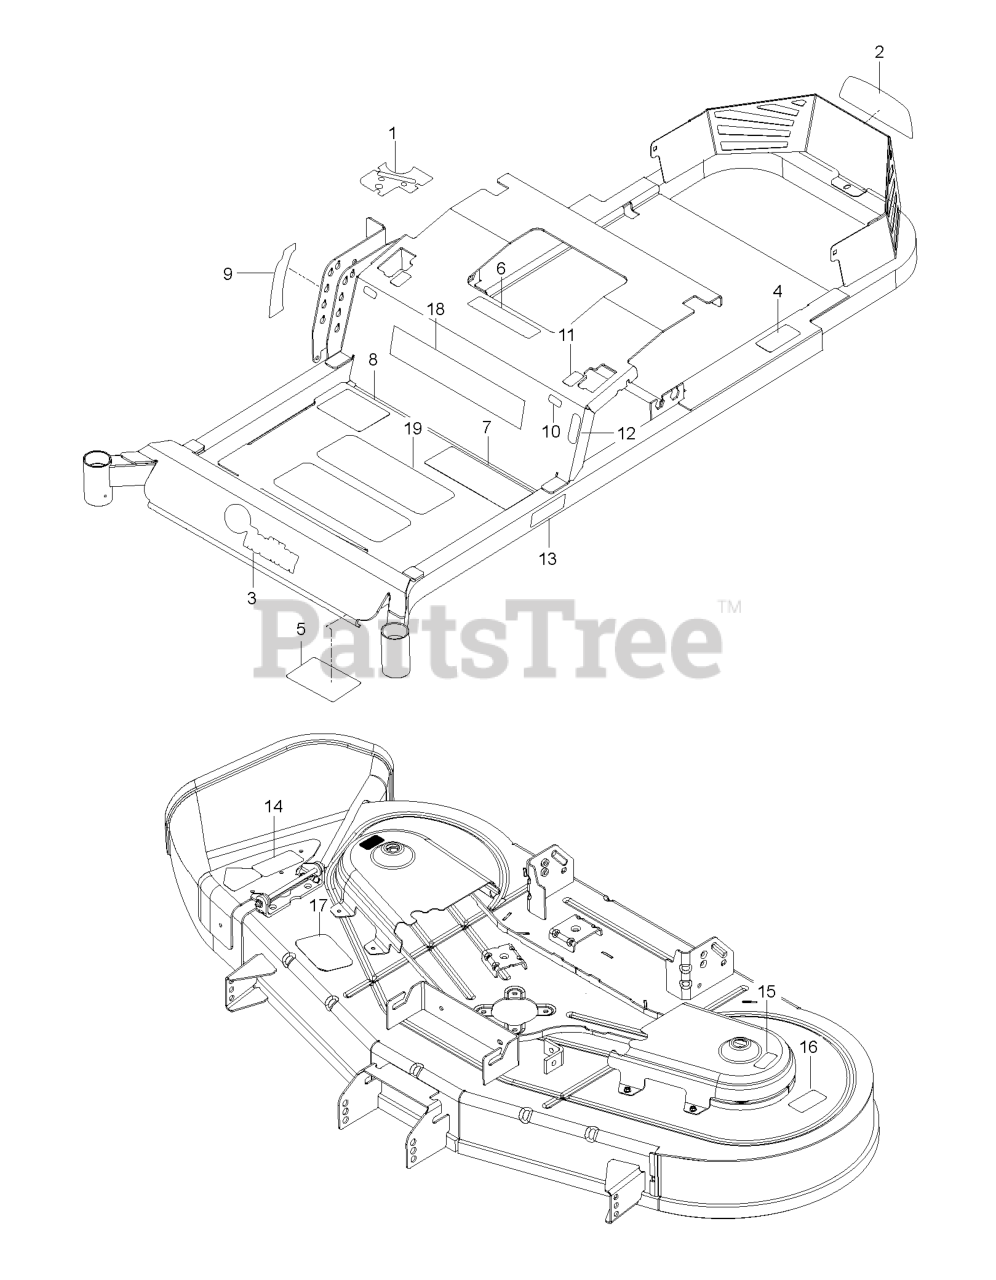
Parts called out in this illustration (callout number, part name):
1	DECAL CTRL PANEL GRAPHIC DECAL
2	DECAL ZTR BRAND GRAPHIC DECAL.
3	DECAL ZTR BRAND GRAPHIC DECAL.
4	DECAL, DO NOT TOW
5	DECAL, SERVICE
6	EURO DECAL-BATTERY WARNIN6
7	DECAL ZTR WARNING DECAL DECAL.
8	DECAL ZTR STARTING DECAL
9	DECAL.ZTR.HTADJ.LTRD.RZ2015PPR
10	DECAL.ZTR.TRACKING.GRAPHIC
11	DECAL.ZTR.MTNCONTROL.2015.PPRO
12	DECAL.ZTR.TRACKING.GRAPHIC
13	DECAL ZTR SIDE RAIL GRAPHIC DE
14	DECAL DECK WARNING GRAPHIC DEC
15	DECAL.DECK.CLEARCUT.NOSTEP
16	DECAL DECK DECAL DECAL.DECK.54
17	DECAL BELT ROUTING DECAL DECAL
18	DECAL ZTR MODEL NUMBER DECAL.Z
19	ANTI-SKID PAD
